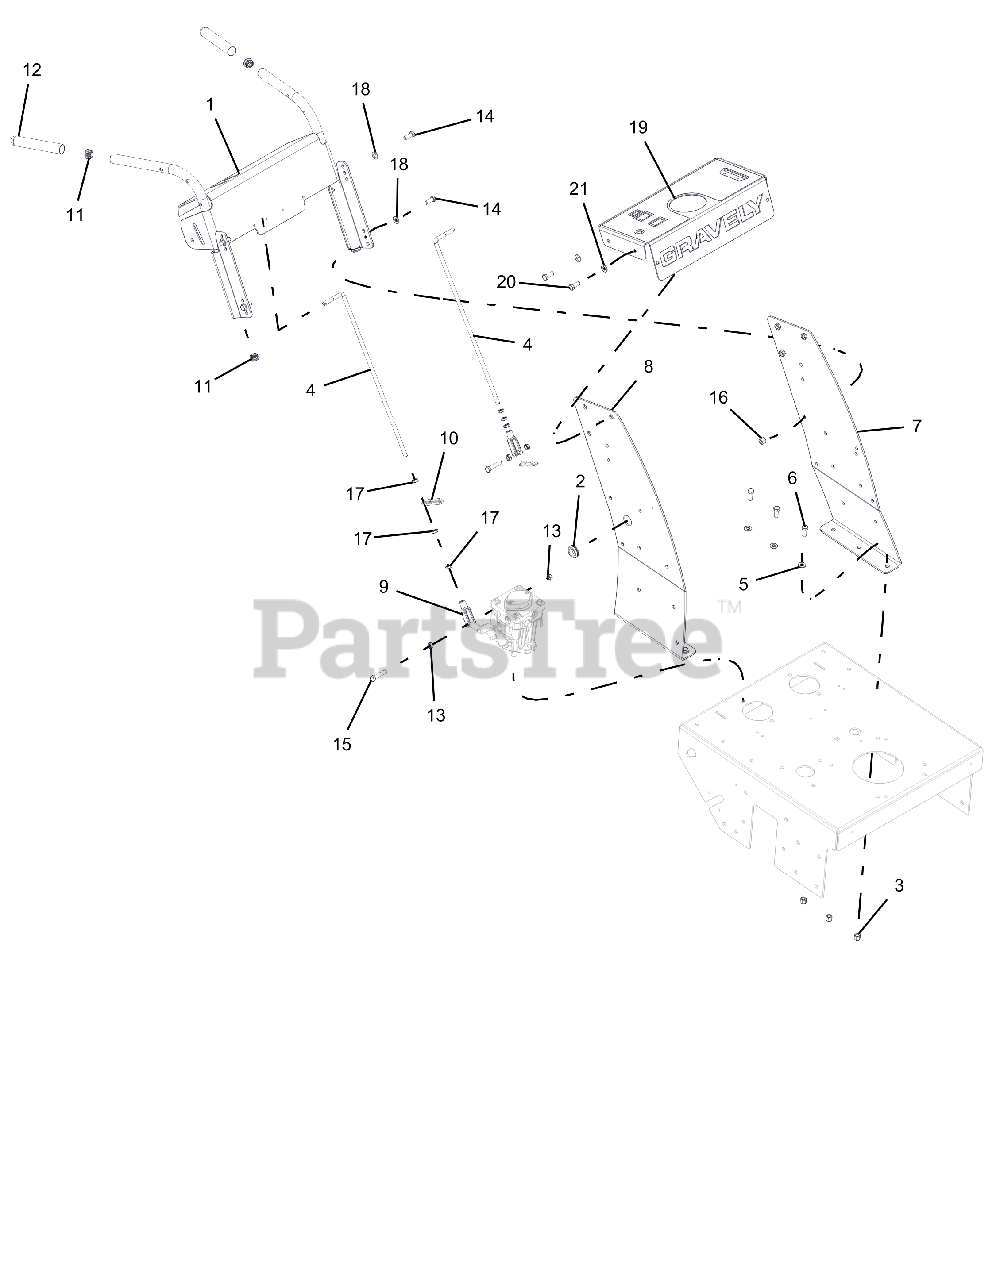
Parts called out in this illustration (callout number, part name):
1	WLDMT, HANDLEBAR PRO-WALK
2	GROMMET:RUB:.88IDx1.38ODX.14GR
3	NUT-LK-NYL .38-16 YWZC
4	ROD, SPD CONTROL
5	WSHR-FL-STL.406X.812X.065 YWZ
6	BLT-HEX .38-16X1.00 GR5 YWZC
7	WLDMT, LH UPRIGHT TOWER 22"-BLACK
8	WLDMT, RH UPRIGHT TOWER PG WD-BLACK
9	CLEVIS, .38-24 ADJ.
10	SPRG, EXTENSION
11	CAPLUG, HANDLEBAR
12	GRIP, HANDLEBAR
13	@NUT-LK-CTR-JAM .375-16 YWZC
14	BLT-HEX .38-16X1.00 GR5 YWZC
15	BLT-HEX .38-16X1.75 GR5 YWZC
16	NUT-LK-NYL .38-16 YWZC
17	NUT-JAM .375-24 YWZC
18	WSHR-FL-STL.406X.812X.065 YWZ
19	ASM, CONSOLE UPR, GRAV, 48/52/61 LPG
20	BLT-HEX .38-16X1.00 GR5 YWZC
21	WSHR-FL-STL.406X.812X.065 YWZ
